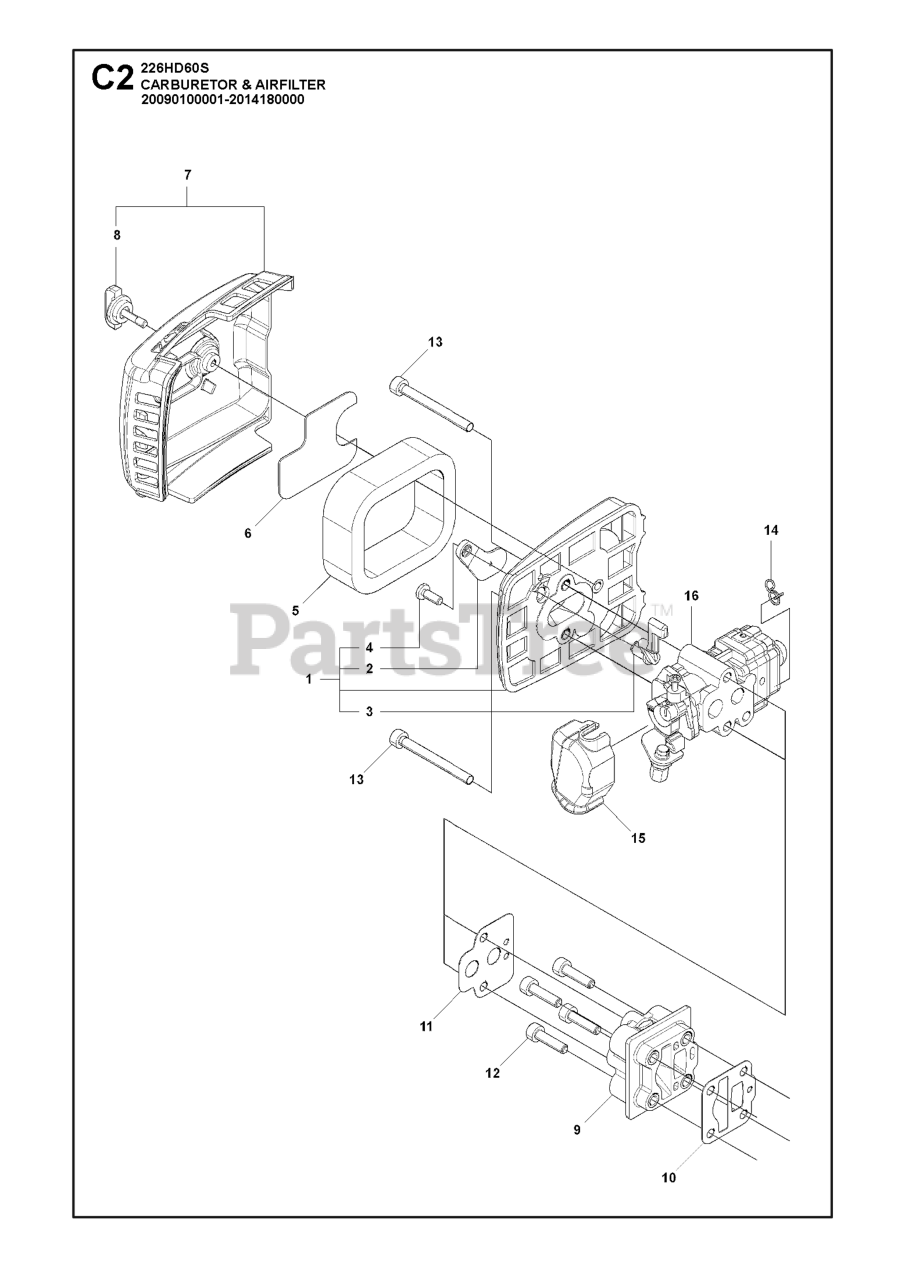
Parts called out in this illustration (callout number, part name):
2	PLATE, choke
4	SCREW
7	COVER ASSY
8	KNOB
11	GASKET, CARB (RPLS T155113131)
16	CARBURETOR ASSY
